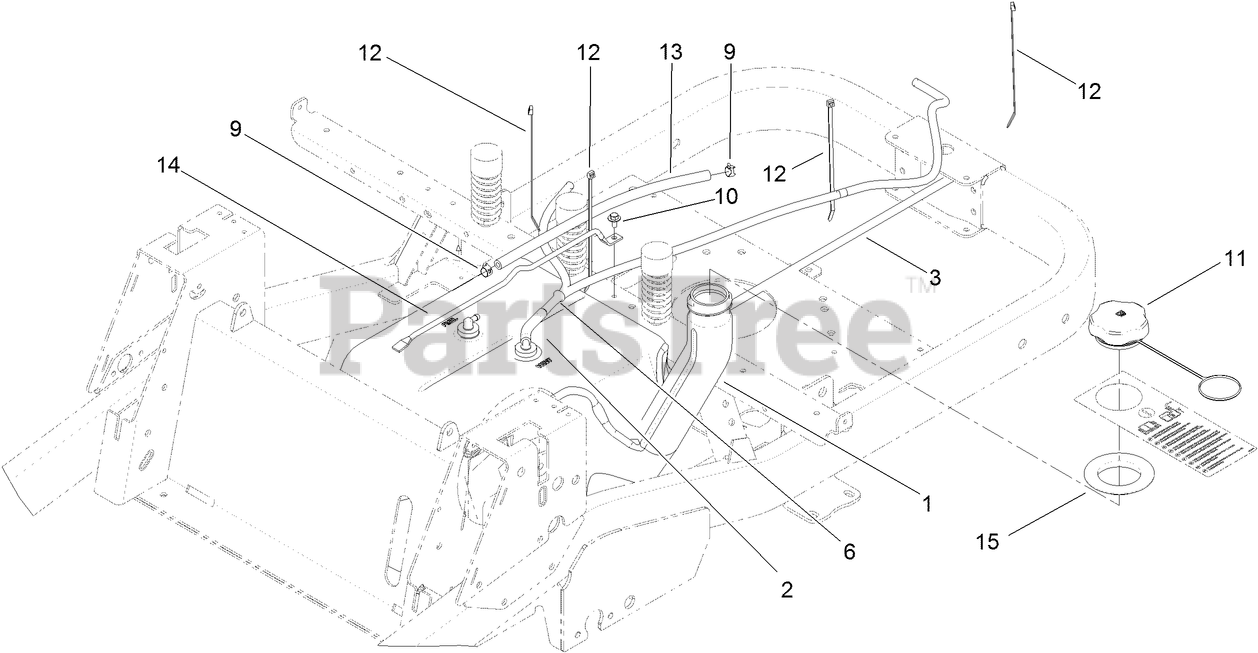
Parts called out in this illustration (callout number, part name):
1	FUEL TANK ASM
2	HOSE-FUEL
3	HOSE-FUEL
6	ADAPTER-ORIFICE
9	CLAMP-HOSE
10	SCREW-HHFTF
11	CAP-FUEL
12	TIE-CABLE
13	HOSE-FUEL
14	ROD-TANK, GAS
15	SEAL-TANK
